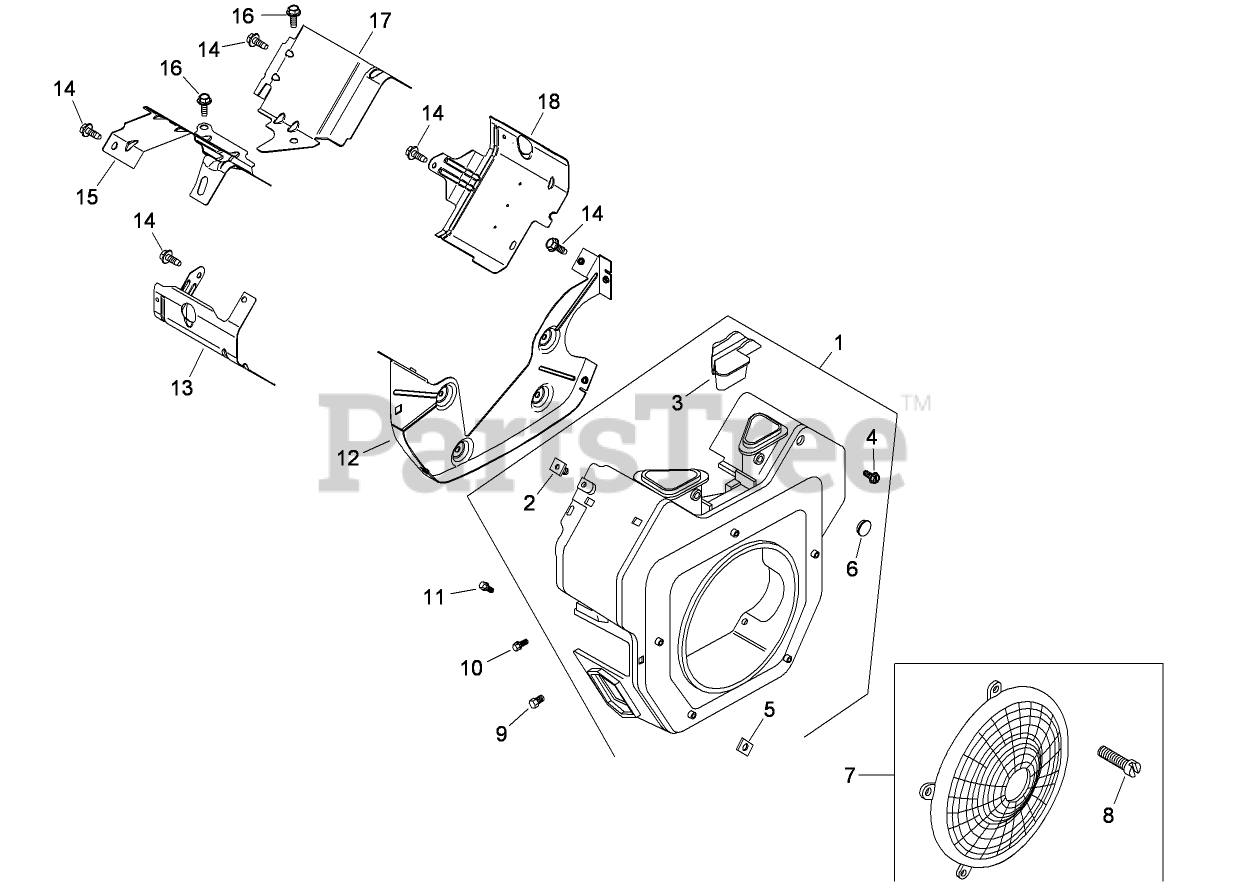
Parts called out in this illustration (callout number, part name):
1	Blower Housing ASM (Includes 2-6)
2	NUT-PLASTIC
3	Cover-Housing, Blower
4	PLUG-BUTTON (9/16)
5	Nut-Plastic
6	Screw-WSH HD Tap (8-18X.50)
7	Fixed Guard Kit (Includes 8)
8	SCREW-SEMS
9	SCREW-FLANGE, THREAD FORMING (M5X.80X16)
10	SCREW-FLANGE, THREAD FORMING (M5X0.8X16)
11	SCREW-FLANGE, THREAD FORMING (M5X.8X20)
12	PLATE-BACKING
13	BAFFLE-BARREL, CYLINDER (No. 2 SIDE)
14	SCREW-FLANGE, THREAD FORMING (M6X1.0X16)
15	BAFFLE-VALLEY (No. 2 SIDE)
16	SCREW-HHFTF (M5X.80X10)
17	BAFFLE-VALLEY (No. 1 SIDE)
18	BARREL-CYLINDER (No.1 SIDE)
